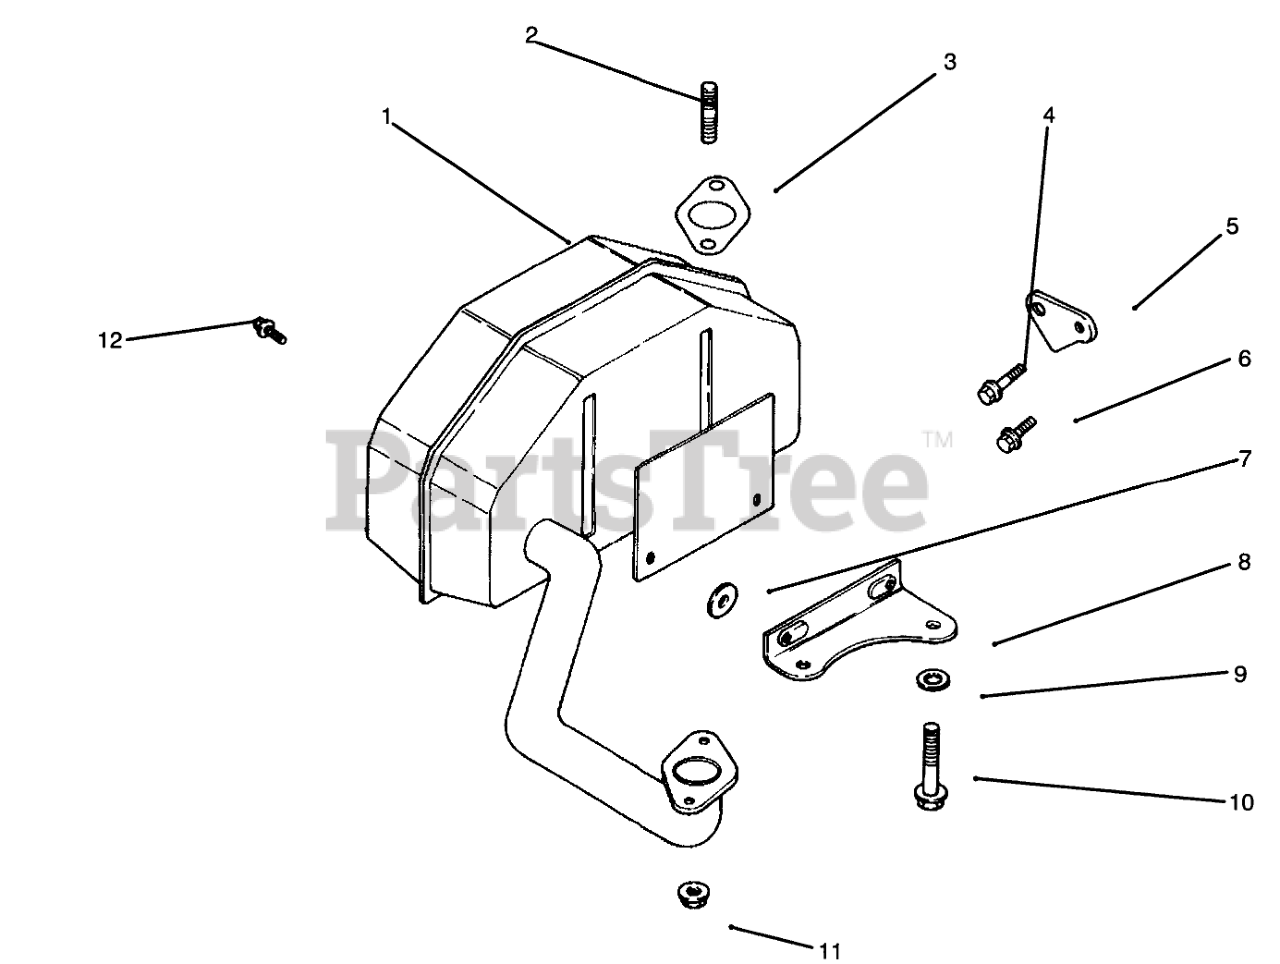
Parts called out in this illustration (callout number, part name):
1	Muffler
2	Stud
3	Gasket-Exhaust
6	Screw
7	Washer
8	Bracket-Muffler
9	Washer
11	Nut-Muffler
12	Screw
